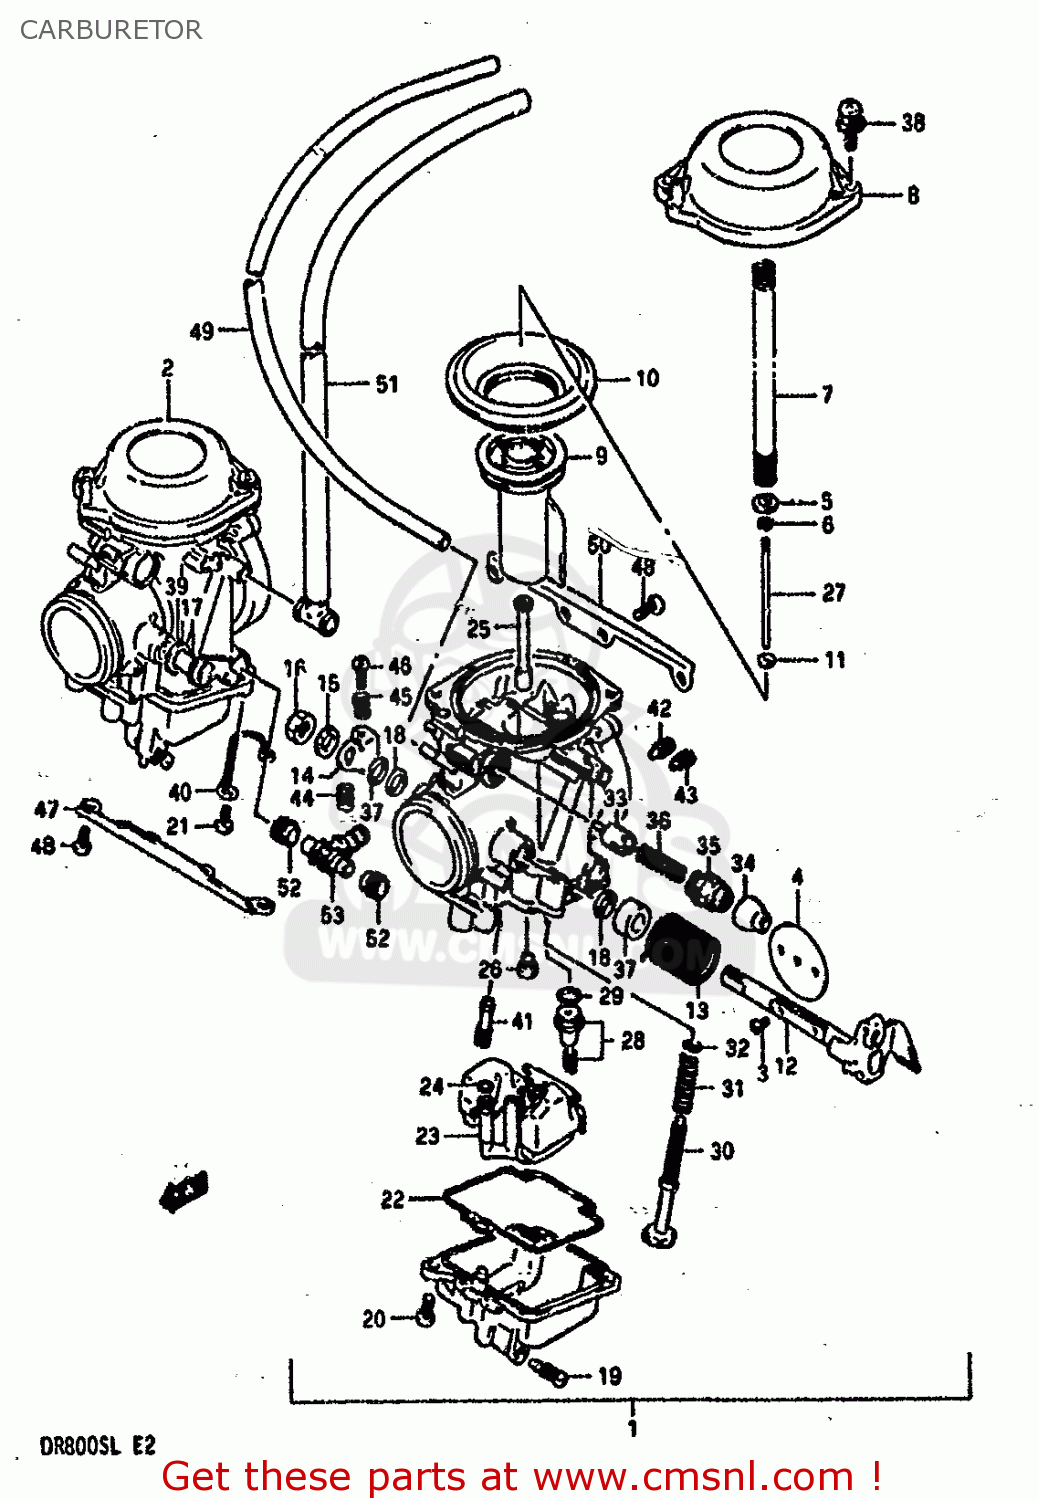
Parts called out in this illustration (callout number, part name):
1	CARBURETOR ASSY,LH
2	CARBURETOR ASSY,RH
3	SCREW
4	VALVE,THROTTLE (115)
5	RING
6	CLIP
7	SPRING
8	COVER,DIAPHRAGM
9	VALVE PISTON
10	DIAPHRAGM
11	RING
12	SHAFT ASSY
13	SPRING
14	LEVER,THROTTLE
15	WASHER,LOCK,8.
16	NUT
17	SHAFT ASSEMBLY
18	SEAL
19	PLUG,DRAIN
20	SCREW
21	SCREW
22	GASKET,FLOAT CHAMBER (NAS)
23	FLOAT ASSY
24	O RING
25	JET,NEEDLE(O-5)
26	JET,MAIN(117.5)
27	NEEDLE,JET
28	VALVE ASSEMBLY,NEEDLE
29	O-RING,NEEDLE VALVE
30	SCREW
31	SPRING
32	WASHER
33	PLUNGER ASSY
34	CAP
35	HOLDER,GUIDE
36	SPRING
37	RING
38	SCREW
39	GASKET,THROTTLE SHAFT (NAS)
40	CLIP
41	JET(40)
42	JET,AIR(1.1)
43	JET,AIR(0.6)
44	SPRING,THROTTLE SCREW
45	SPRING
46	SCREW
47	PLATE
48	SCREW
49	HOSE
50	PLATE
51	HOSE
52	SEAL
53	NIPPLE
